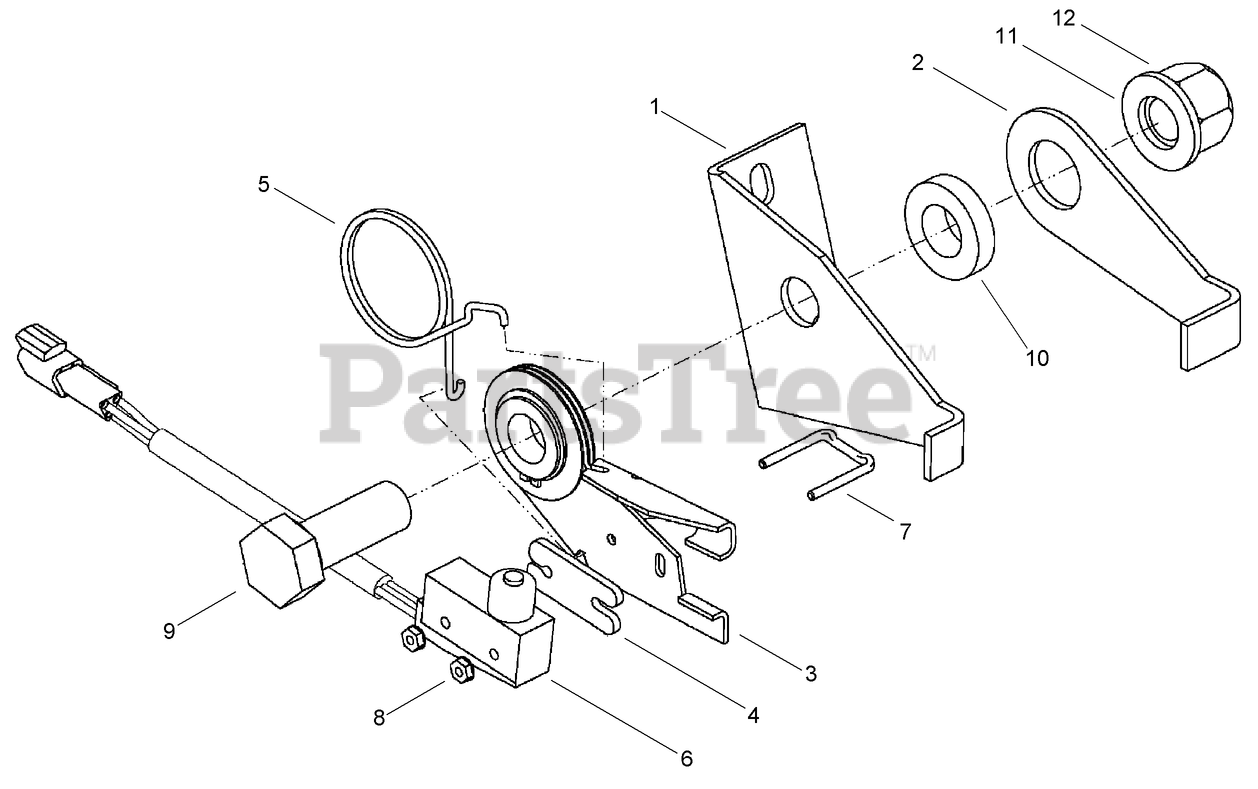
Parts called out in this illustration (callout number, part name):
1	PLATE-MOUNTING
2	PLATE-ACTUATOR
3	NEUTRAL SWITCH MOUNTING ASM
4	SPACER-SWITCH
5	SPRING-CENTERING
6	SWITCH-NEUTRAL START
7	BOLT-U, SWITCH MTG (H435814)
8	NUT - KEPS Ext T Wshr #6 - 32 UNC ZP
10	HUB-ACTUATOR
11	WASHER-FLAT
12	NUT-Prev Trq 3/4 GRC CAD Direct
